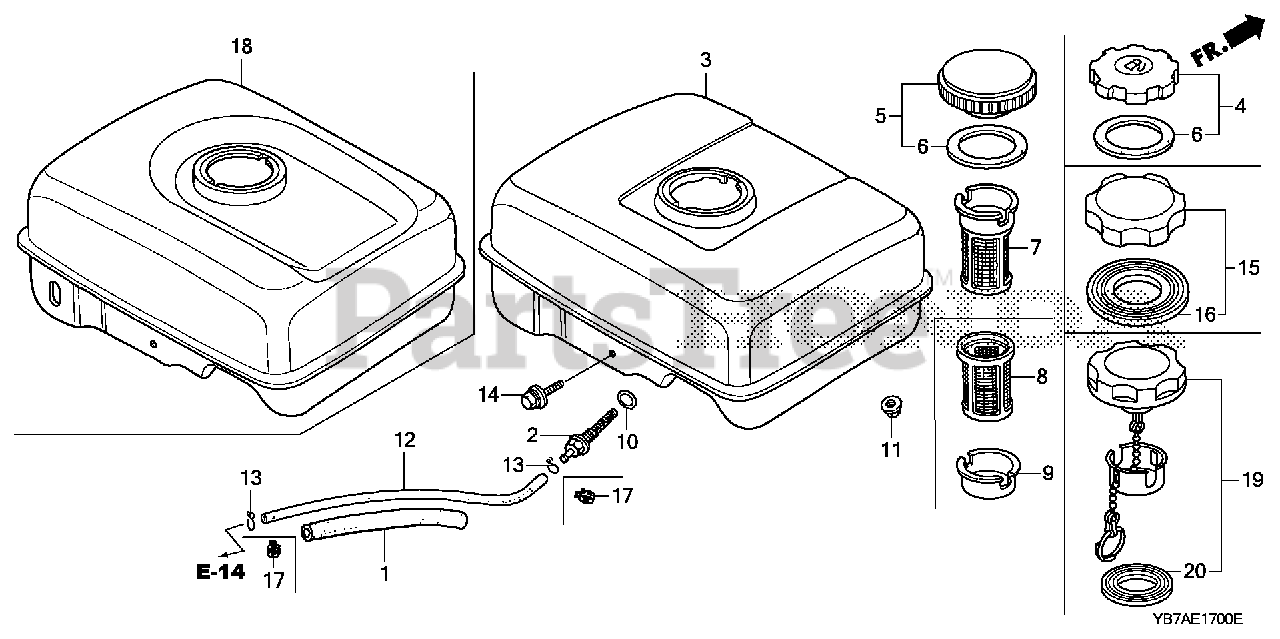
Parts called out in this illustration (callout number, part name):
1	RUBBER, SUPPORTER (107MM)
2	JOINT, FUEL TANK
3	TANK, FUEL *NH31* (MCKINLEY WHITE)
7	FILTER, FUEL
10	O-RING (13.5X1.5) (ARAI)
10	O-RING (14MM) (NOK)
11	NUT, FLANGE (6MM)
12	BULK HOSE, FUEL (4.5X3000) (4.5X140)
13	CLIP, TUBE (B8)
14	BOLT, FLANGE (6X29)
15	CAP, FUEL FILLER (CHROME PLATED)
16	GASKET, FUEL FILLER CAP (39X62X3) (TOUYOUSYA)
